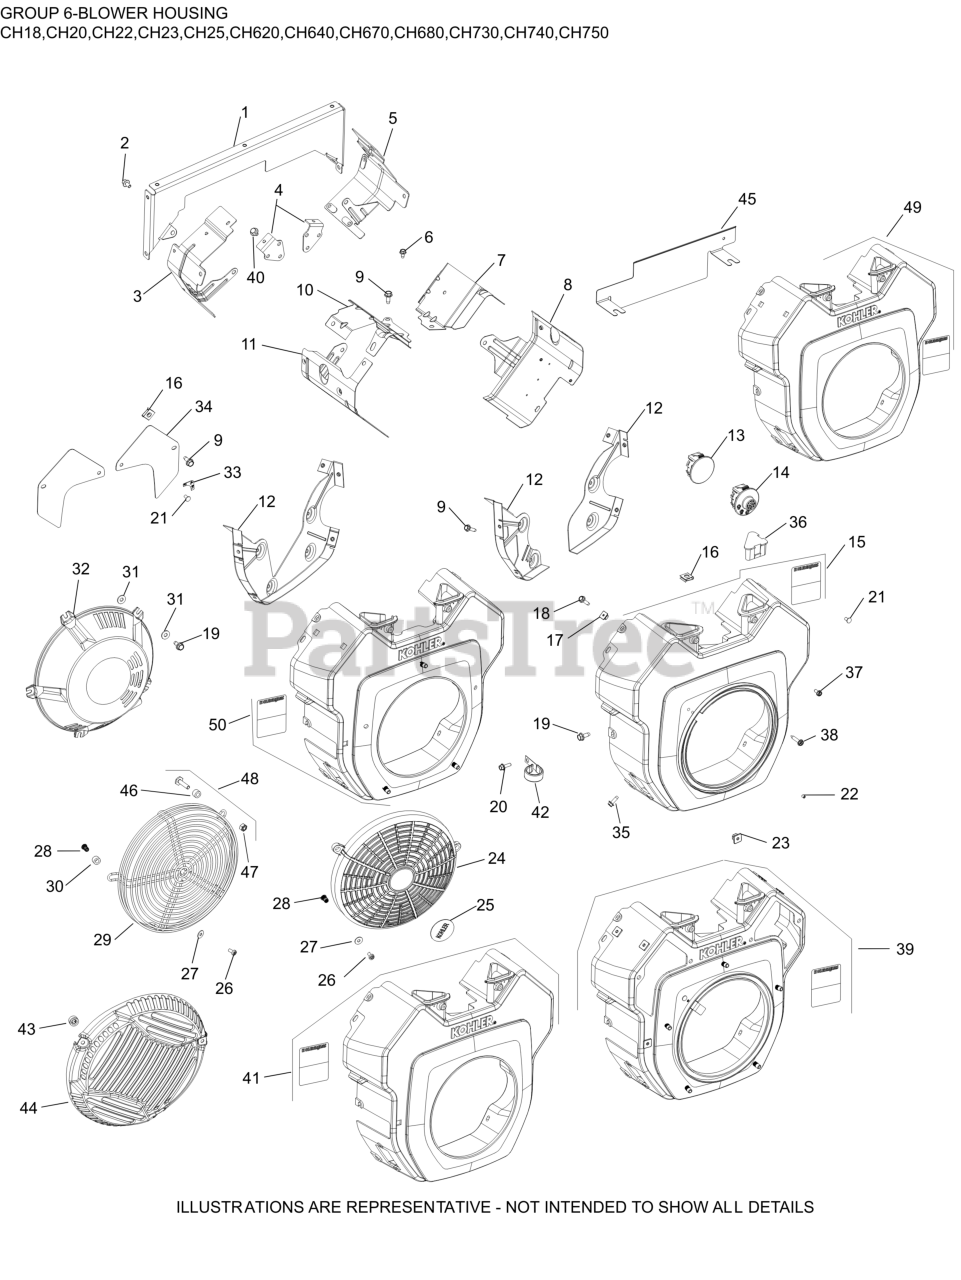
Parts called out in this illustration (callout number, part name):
6	SCREW, THREAD FORMING
7	BAFFLE, VALLEY #1 CYLINDER
8	KIT, CYL BAFFEL #1 SIDE
9	SCREW, THREAD FORMING
10	BAFFLE, VALLEY #2 CYLINDER
11	BAFFLE, LEFT BARREL
12	KIT, BACKING PLATE
15	HOUSING, BLOWER
19	SCREW, THREAD FORMING
35	SCREW, THREAD FORMING
